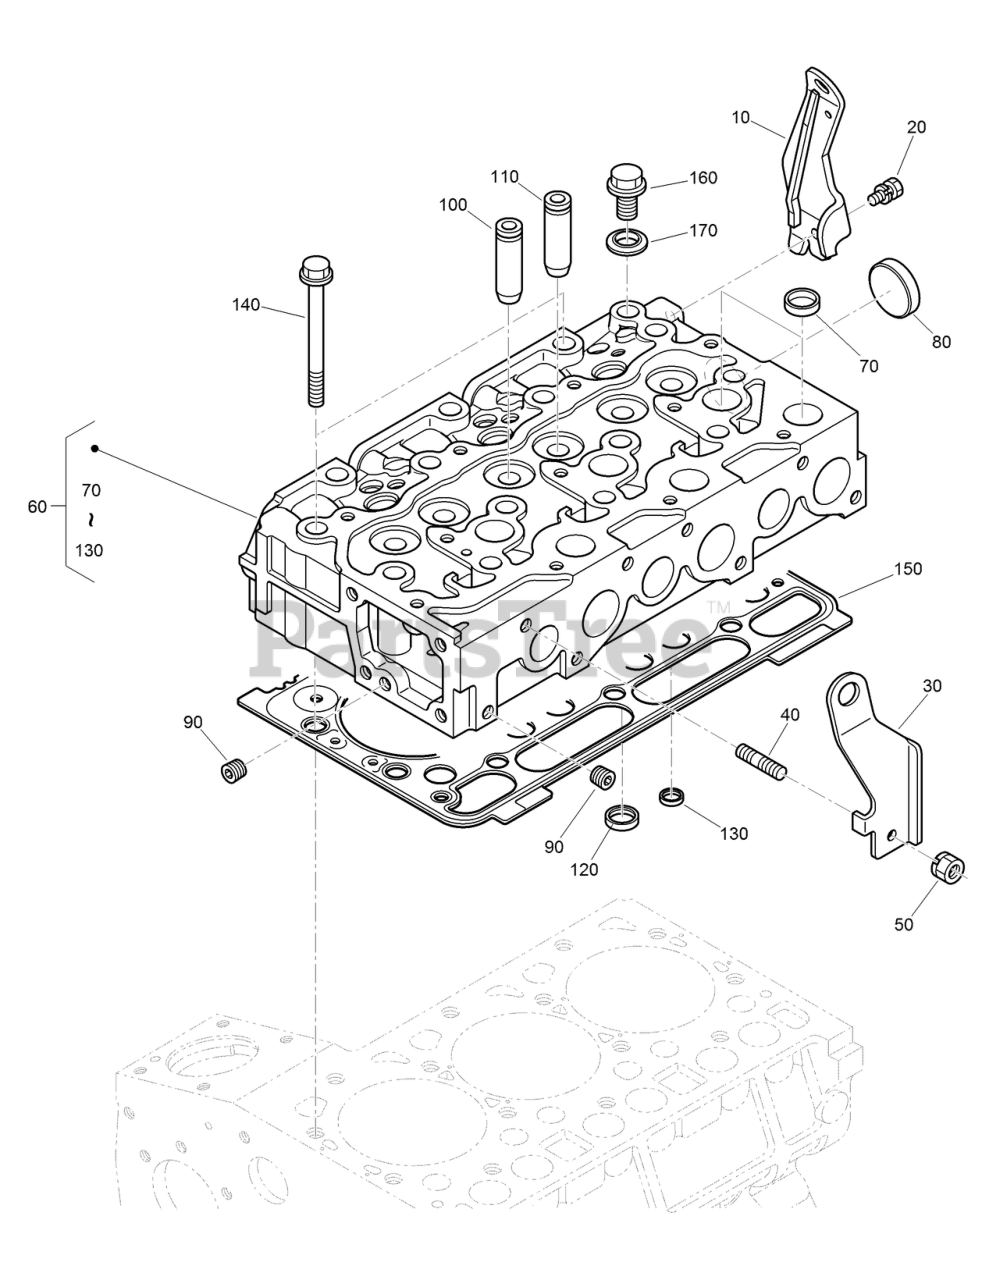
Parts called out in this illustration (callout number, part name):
10	HOOK-ENGINE, REAR
30	HOOK-ENGINE, FRONT
40	BOLT-STUD
60	HEAD-CYLINDER
70	PLUG-CUP
80	CAP-SEALING
100	GUIDE-VALVE, INLET
110	GUIDE-VALVE, EXHAUST
120	SEAT-VALVE, INLET
130	SEAT-VALVE, EXHAUST
140	BOLT-HEAD, CYLINDER
150	GASKET-HEAD, CYLINDER
170	WASHER-SEAL
